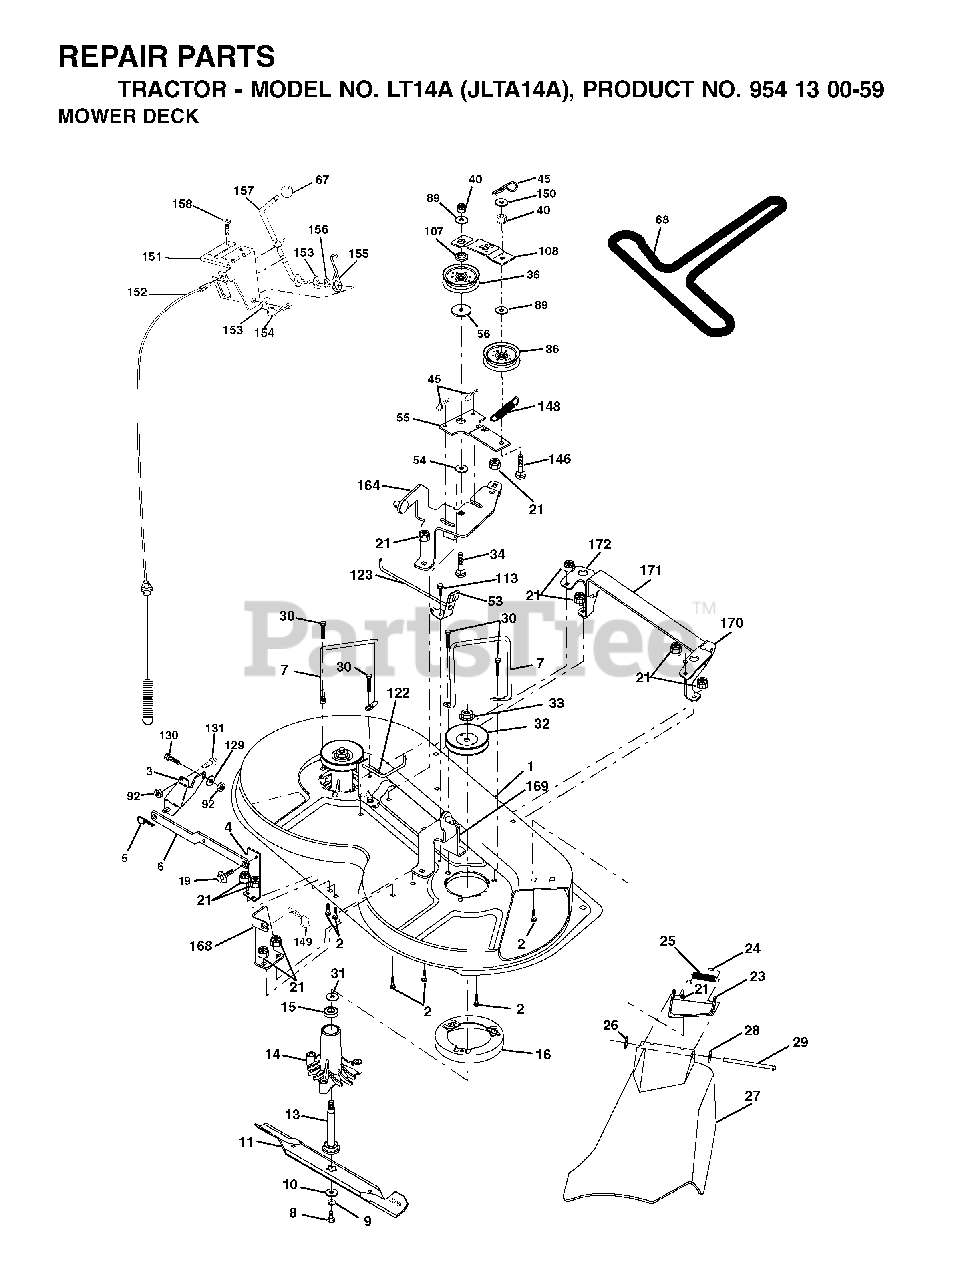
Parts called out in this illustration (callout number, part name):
2	BOLT
3	BRKT ASM SWAY BAR
5	RETAINER-SPRNG RB
6	BAR SWAY DECK
7	KEEPER LH
8	BLADE BOLT
9	LOCKWASHER
10	WASHER.BLADE
11	BLADE, HI-LIFT 36" PREMIUM
13	SHAFT ASM VENT
14	HSG MANDREL
16	STRIPPER, MWR ROUND
19	BOLT SHD 5/16-18
21	LOCKNUT
23	BRACKET ASM DEFLECTOR
24	CAP-SLEEVE LT
25	SPRING TORSION
26	NUT PUSH M
28	WASHER
29	HINGE ROD
30	SCREW, WASHER HEAD
31	WASHER
32	PULLEY, MANDREL
33	NUT, FLG TOPLOCK 9/16"
34	BOLT
36	FLAT IDLER PULLEY
40	LOCKNUT
45	RETAINER M
53	BRAKE ASSEMBLY
54	HARDENED WASHER
55	IDLER ARM
56	SPACER.RETAINER.MOWER
67	KNOB T (3/8 HOLE)
68	V-BELT.MOWER.
89	WASHER GT
92	NUT
107	SPACER.IDLER.ARM
108	STIFFENER.IDLER.ARM
129	WASHER
131	BOLT D
146	BOLT, CARRIAGE IDLER
148	IDLER RETURN SPRING
149	SPRING.RETAINER.YELLOW.ZINC
150	WASHER PM
151	BRACKET, CLUTCH CABLE
153	WASHER FLAT 3/8"
154	SPRING RETAINER
155	SPRING RETENTION LEVER
156	SPACER CLUTCH CABLE
157	ROD CLUTCH CABLE 3/8"
158	SCREW
171	BRACE
